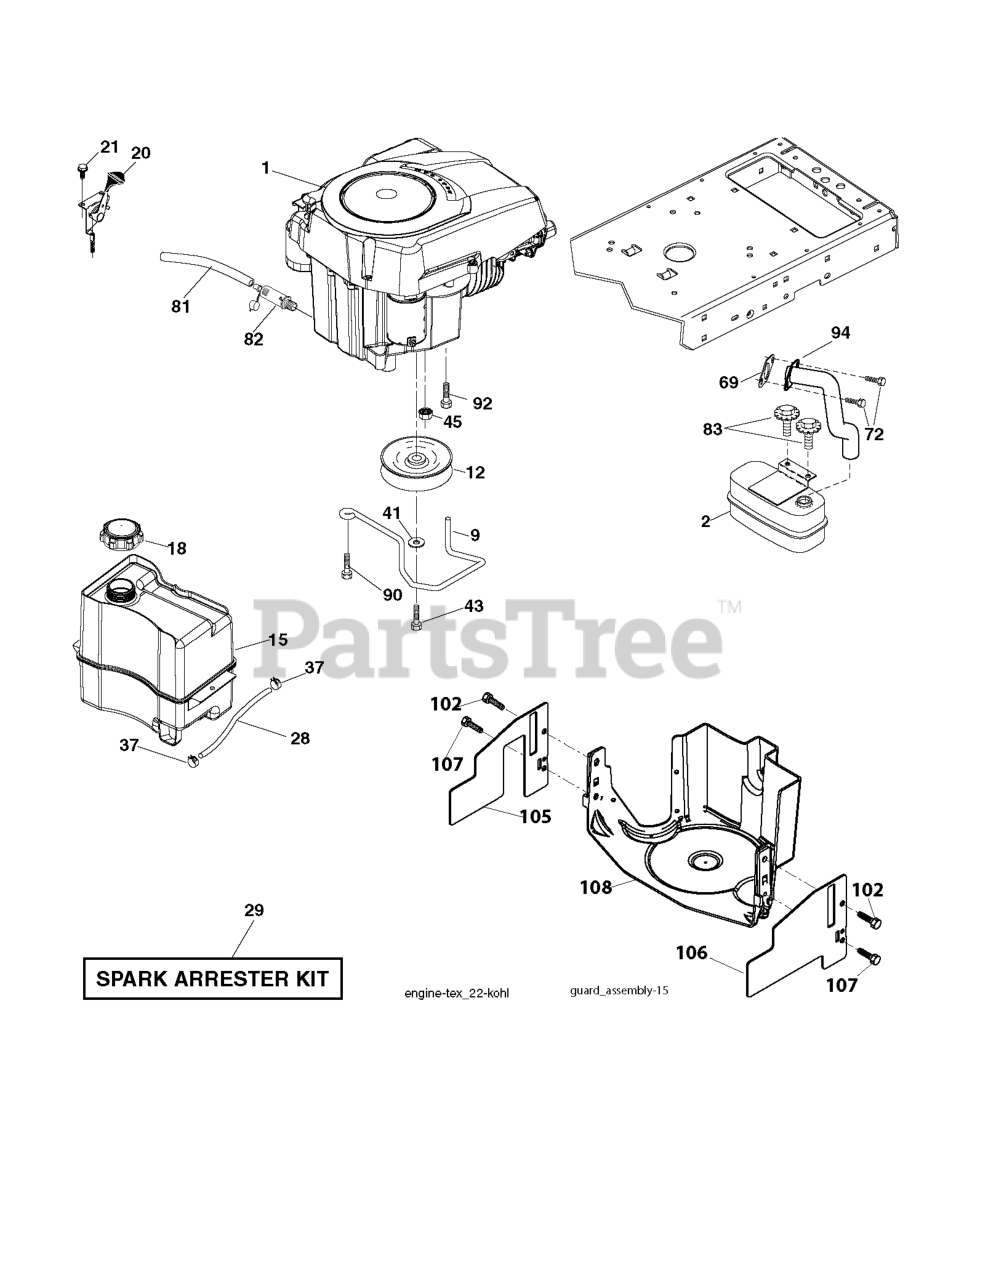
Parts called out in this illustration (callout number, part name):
2	MUFFLER.SINGLE.CYL.KOHL/B&S
9	KEEPER.BELT.ENGINE.3.25 (3 2)
12	PULLEY ENGINE
15	RP TANK FUEL FRT 1.5 GAL
18	FUEL CAP
20	CONTROL.TH/CK.C.
21	SCREW
28	LINE.FUEL.20
29	KIT.SPARK ARRESTOR 794945 B&S
37	HOSE CLAMP
41	LOCKWASHER
43	BOLT HEX 7/16-20X4-1/4"
45	NUT
69	GASKET.EXHAUST.KOHLER
72	SCREW.SOCKET HD.5/16-1
81	TUBE, DRAIN OIL ASM.
82	PLUG DRAIN OIL EASY
83	BOLT.5/16-18UNCX3/4 W/SEMS.BLK
90	SCREW 3/8-16X1
92	SCREW 3/8-16X1
94	RP.TUBE.EXHAUST.KOHL.COURAGE
102	SCREW
107	SCREW.1/4-20X5/8
